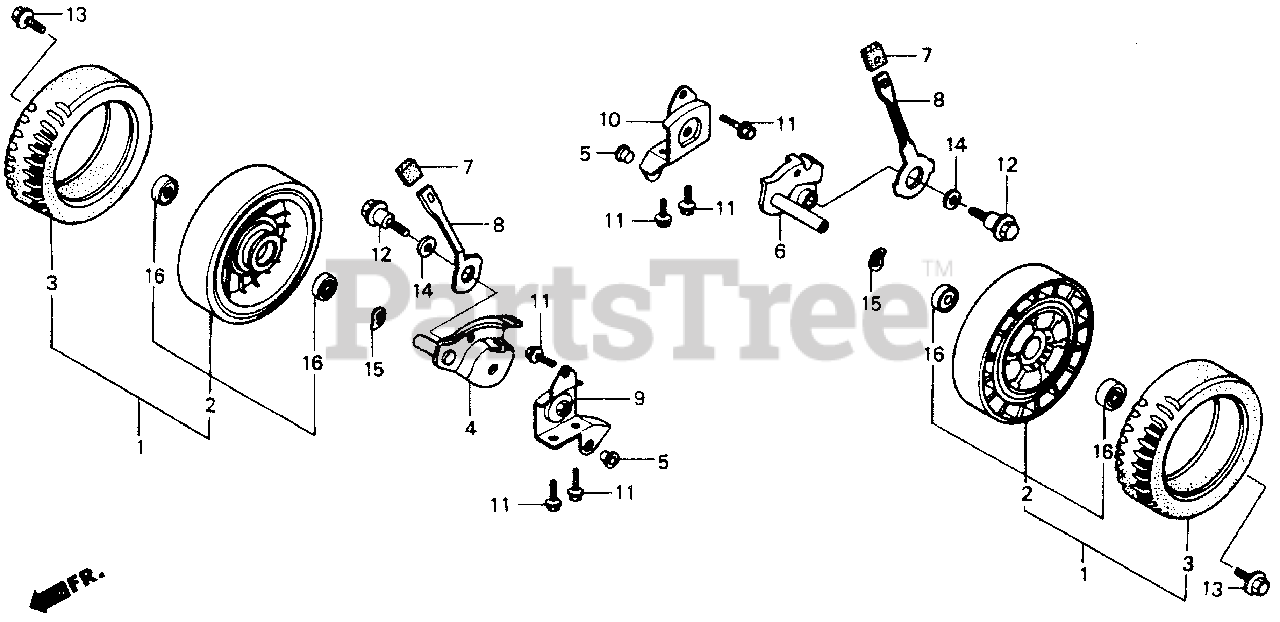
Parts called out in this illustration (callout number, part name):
1	WHEEL (8") (NH31)
2	WHEEL (8") (NH31)
3	TIRE (8 INCH)
4	ARM, R. RR. ADJUSTING
5	BUSH, SAFETY SHIELD (NOT AVAILABLE)
6	ARM, L. RR. ADJUSTING (NOT AVAILABLE)
7	GRIP, ADJUSTER
8	PLATE, RR. ADJUSTING
9	HOLDER, R. RR. ARM
10	HOLDER, L. RR. ARM
11	BOLT, FLANGE (6X12) (CT200)
12	BOLT, RR. ADJUSTING ARM
13	BOLT, WHEEL
15	WASHER, WHEEL
16	BEARING, RADIAL BALL
